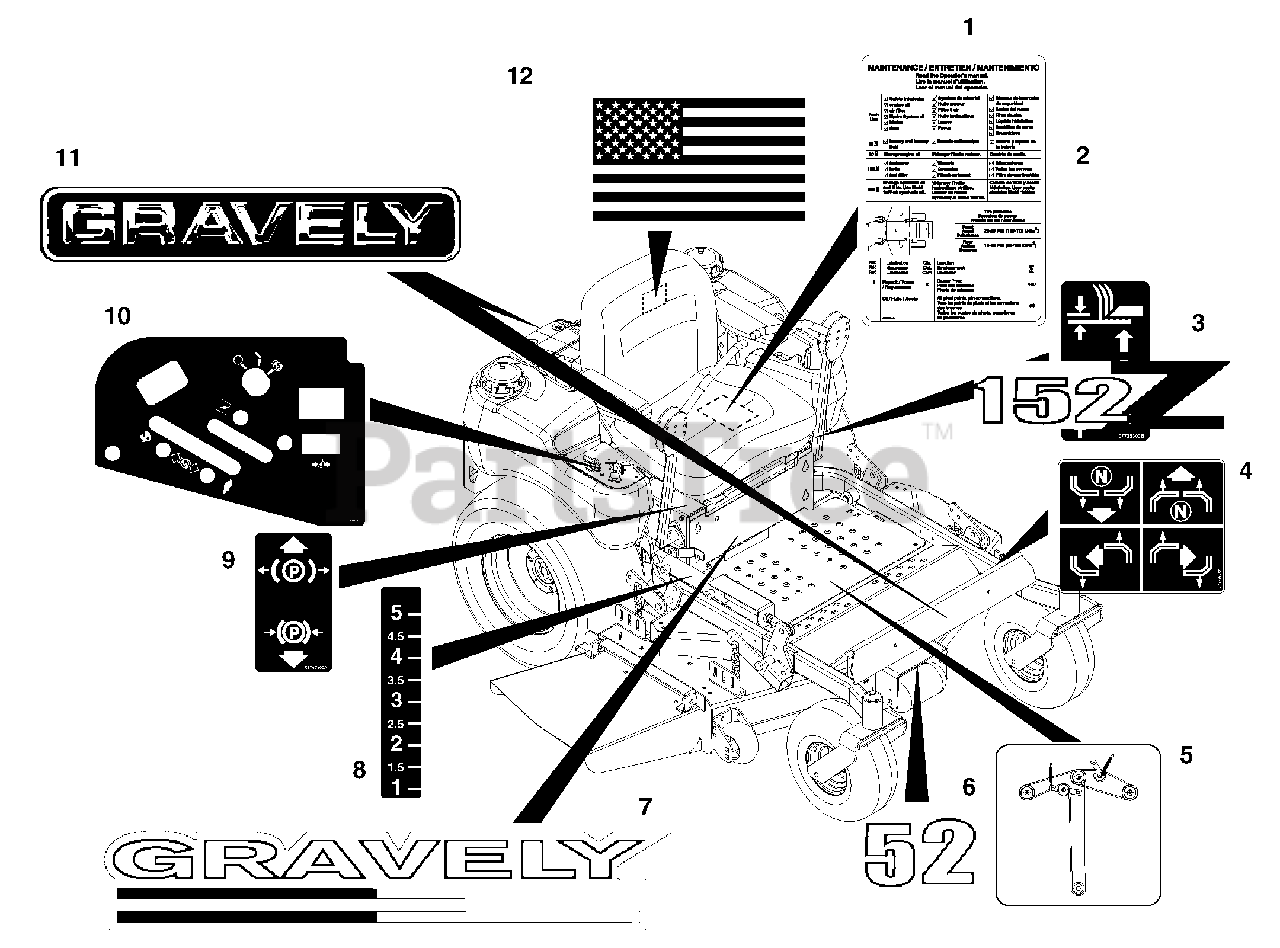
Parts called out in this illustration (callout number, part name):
1	Decal, Service Instructions
2	Decal, Lift Lever
3	Decal, PM 152Z (044, 054)
3	Decal, PM 144Z (042)
3	Decal, PM 148Z (043)
3	Decal, PM 160Z (051, 055)
4	Decal, Instructional Steering
5	Decal, Belt Diagram
6	Decal, 52 (044, 054)
6	Decal, 44 (042)
6	Decal, 48 (043)
6	Decal, 60 (051, 055)
7	Decal, ZT Hood
8	Decal, Height of Cut
9	Decal, Parking Brake Lever
10	Decal, Control Panel
11	Decal, 15" Gravely Logo
12	Decal, American Flag
